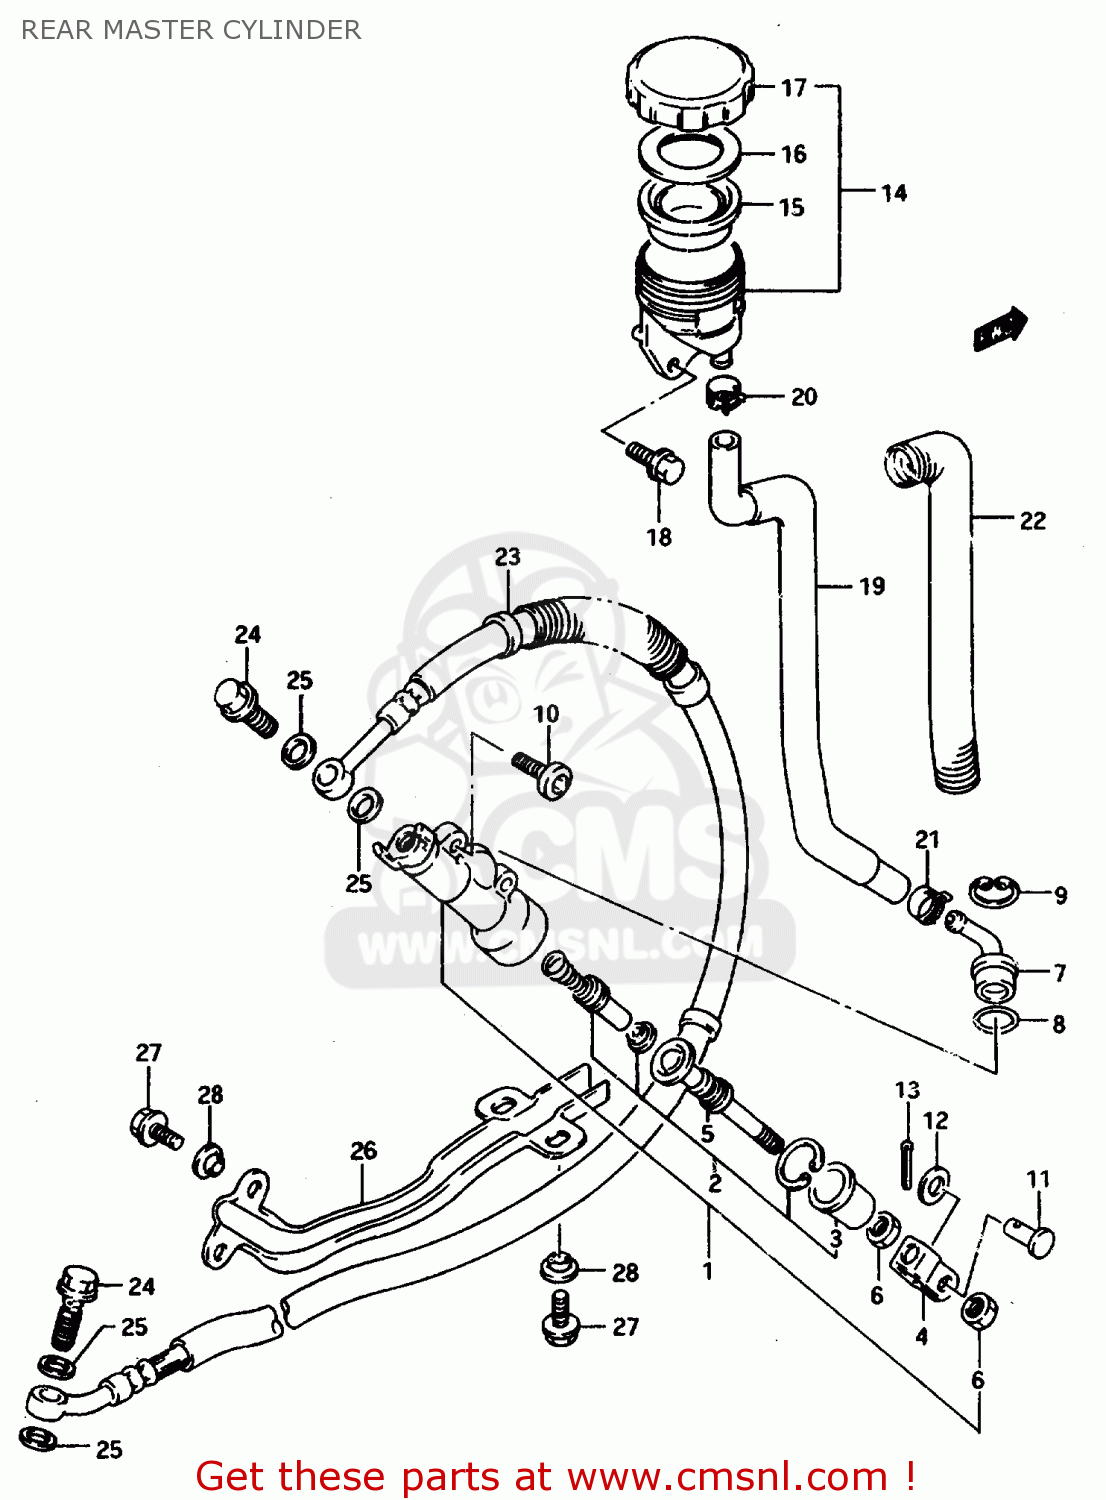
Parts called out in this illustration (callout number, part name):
1	CYLINDER ASSY, REAR MASTER
2	PISTON/CUP SET
3	BOOT
4	YOKE
5	ROD,PUSH
6	NUT
7	CONNECTOR
8	O RING
9	CIRCLIP
10	SCREW(6X16)
11	PIN(8X20)
12	WASHER(8.5X13X1.6)
13	PIN
14	TANK ASSY,RR RESERVOIR
15	DIAPHRAGM
16	PLATE,DIAPHRAGM
17	CAP
18	BOLT
19	HOSE,RESERVOIR TANK
20	CLIP
21	CLIP
22	SHIELD, HOSE HEAT
23	HOSE,RR BRAKE
24	BOLT UNION
25	WASHER(10X15X1.5)
26	PROTECTOR, BRAKE HOSE
27	BOLT 6X12
28	WASHER
